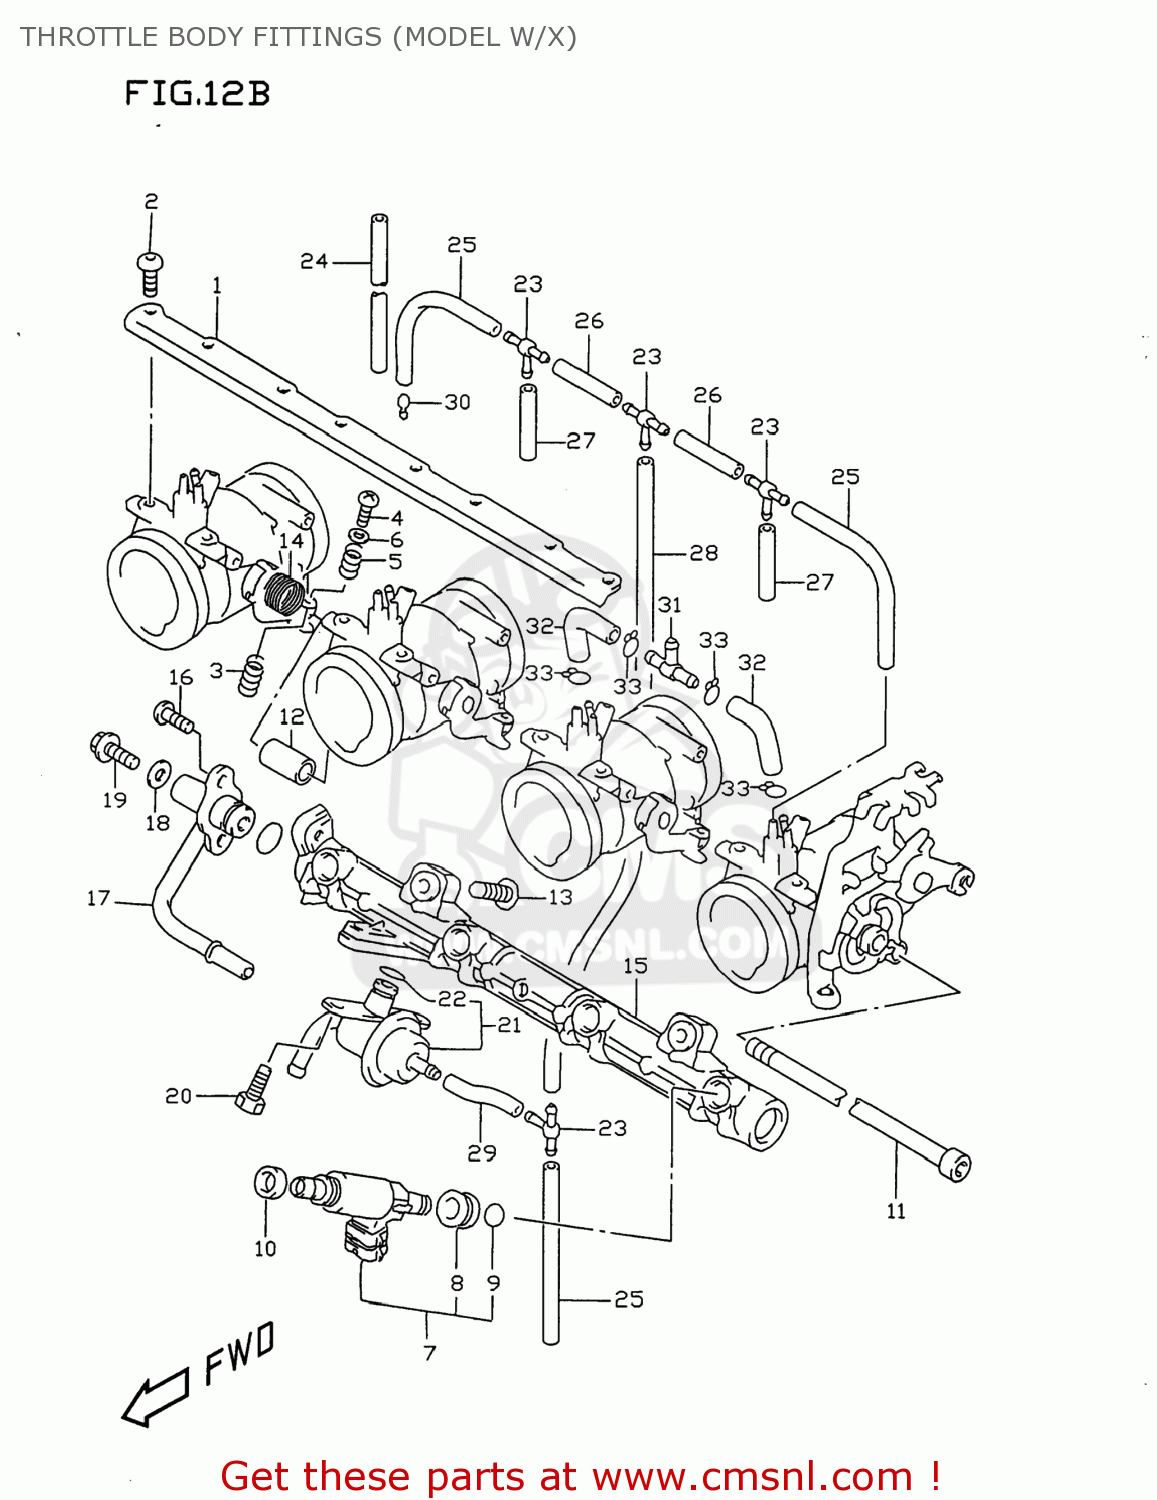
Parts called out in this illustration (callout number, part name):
1	PLATE
2	BOLT
3	SPRING,THROTTLE SCREW
4	SCREW
5	SPRING
6	WASHER
7	INJECTOR ASSEMBLY,FUEL
8	GROMMET
9	O RING
10	CUSHION,FUEL INJECTOR
11	BOLT
12	RING
13	BOLT
14	SPRING
15	DELIVERY PIPE
16	SCREW
17	NIPPLE
18	GASKET(5.8X13X1.2) (NAS)
19	UNION BOLT,AIR VENT
20	BOLT
21	REGULATOR,FUEL
22	O RING
23	3 WAY
24	HOSE(3.5X7.5X600)
25	HOSE(3.5X7.5X600)
26	HOSE(3.5X7.5X600)
27	HOSE(3.5X7.5X600)
28	HOSE(3.5X7.5X600)
29	HOSE(3.5X7.5X600)
30	JET
31	NIPPLE
32	HOSE(5X9X600)
33	CLIP
